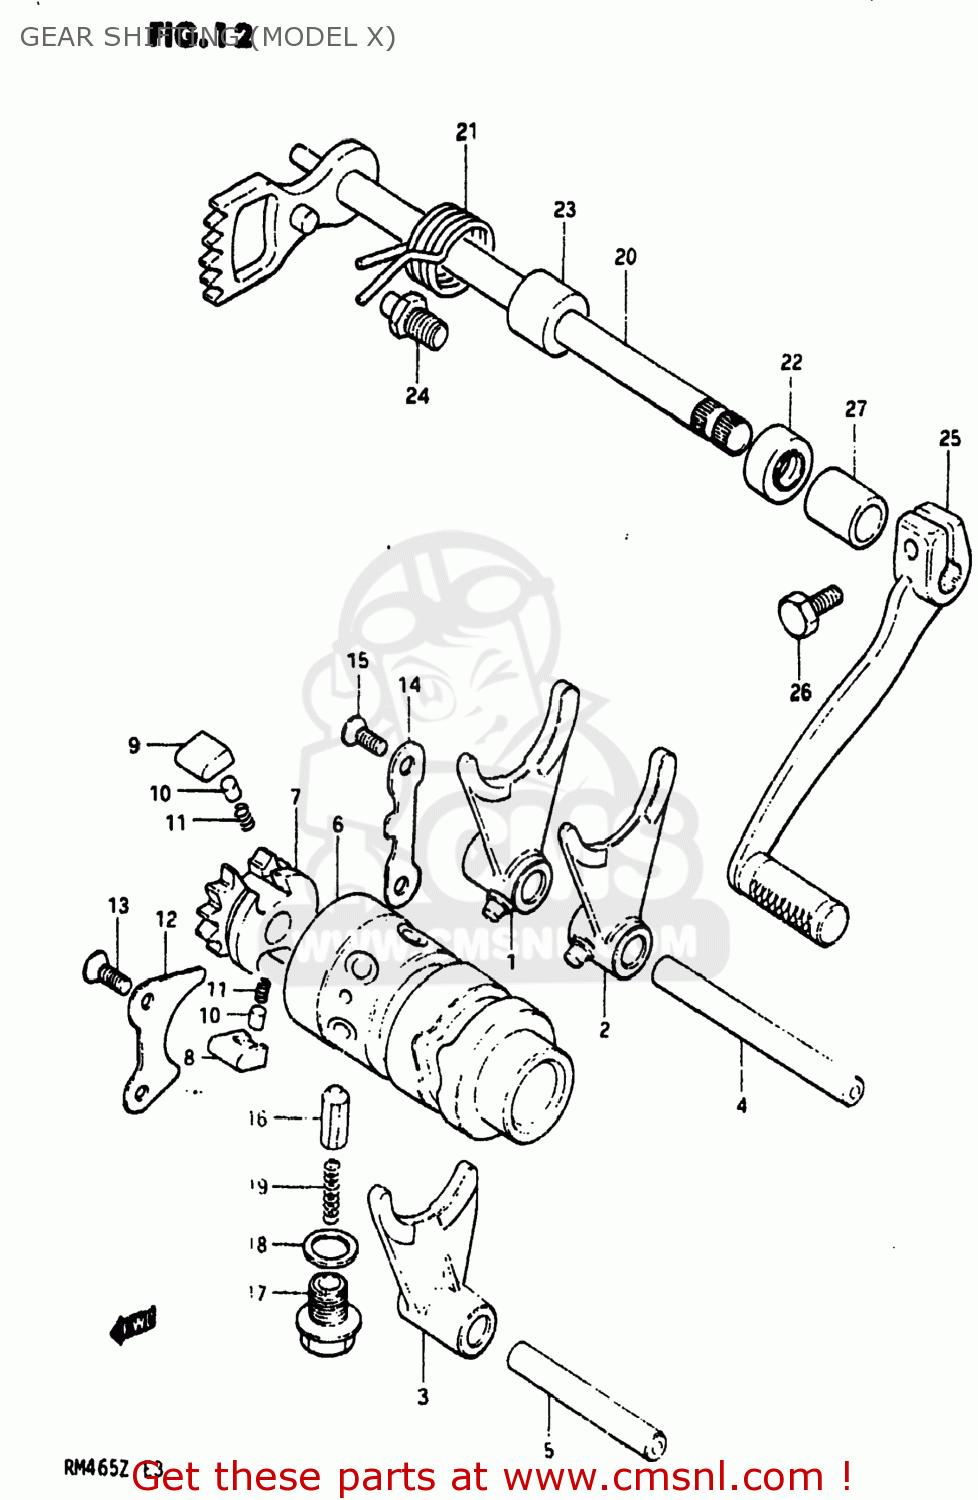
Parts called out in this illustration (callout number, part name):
1	FORK,GEAR SHIFT NO.1
2	FORK,GEAR SHIFT NO.2
3	FORK,GEAR SHIFT NO.3
4	SHAFT,GEAR SHIFT FORK
5	SHAFT,GEAR SHIFT FORK
6	CAM,GEAR SHIFT
7	RETAINER,GEAR SHIFT CAM
8	PAWL,GEAR SHIFT NO.1
9	PAWL,GEAR SHIFT NO.2
10	PIN(5X8)
11	SPRING
12	LIFTER,GEAR SHIFT PAWL
13	SCREW
14	GUIDE,GEAR SHIFT CAM
15	SCREW
16	STOPPER,GEAR SHIFTING
17	BOLT,GEAR SHAFT CAM STOPPER
18	GASKET(14X19.2X2) (NAS)
19	SPRING
20	SHAFT,GEAR SHIFT
21	SPRING
22	OIL SEAL
23	SPACER(12X20X15.3)
24	STOPPER,GEAR SHIFT CAM
25	LEVER,GEAR SHIFT
26	BOLT
27	CUSHION
